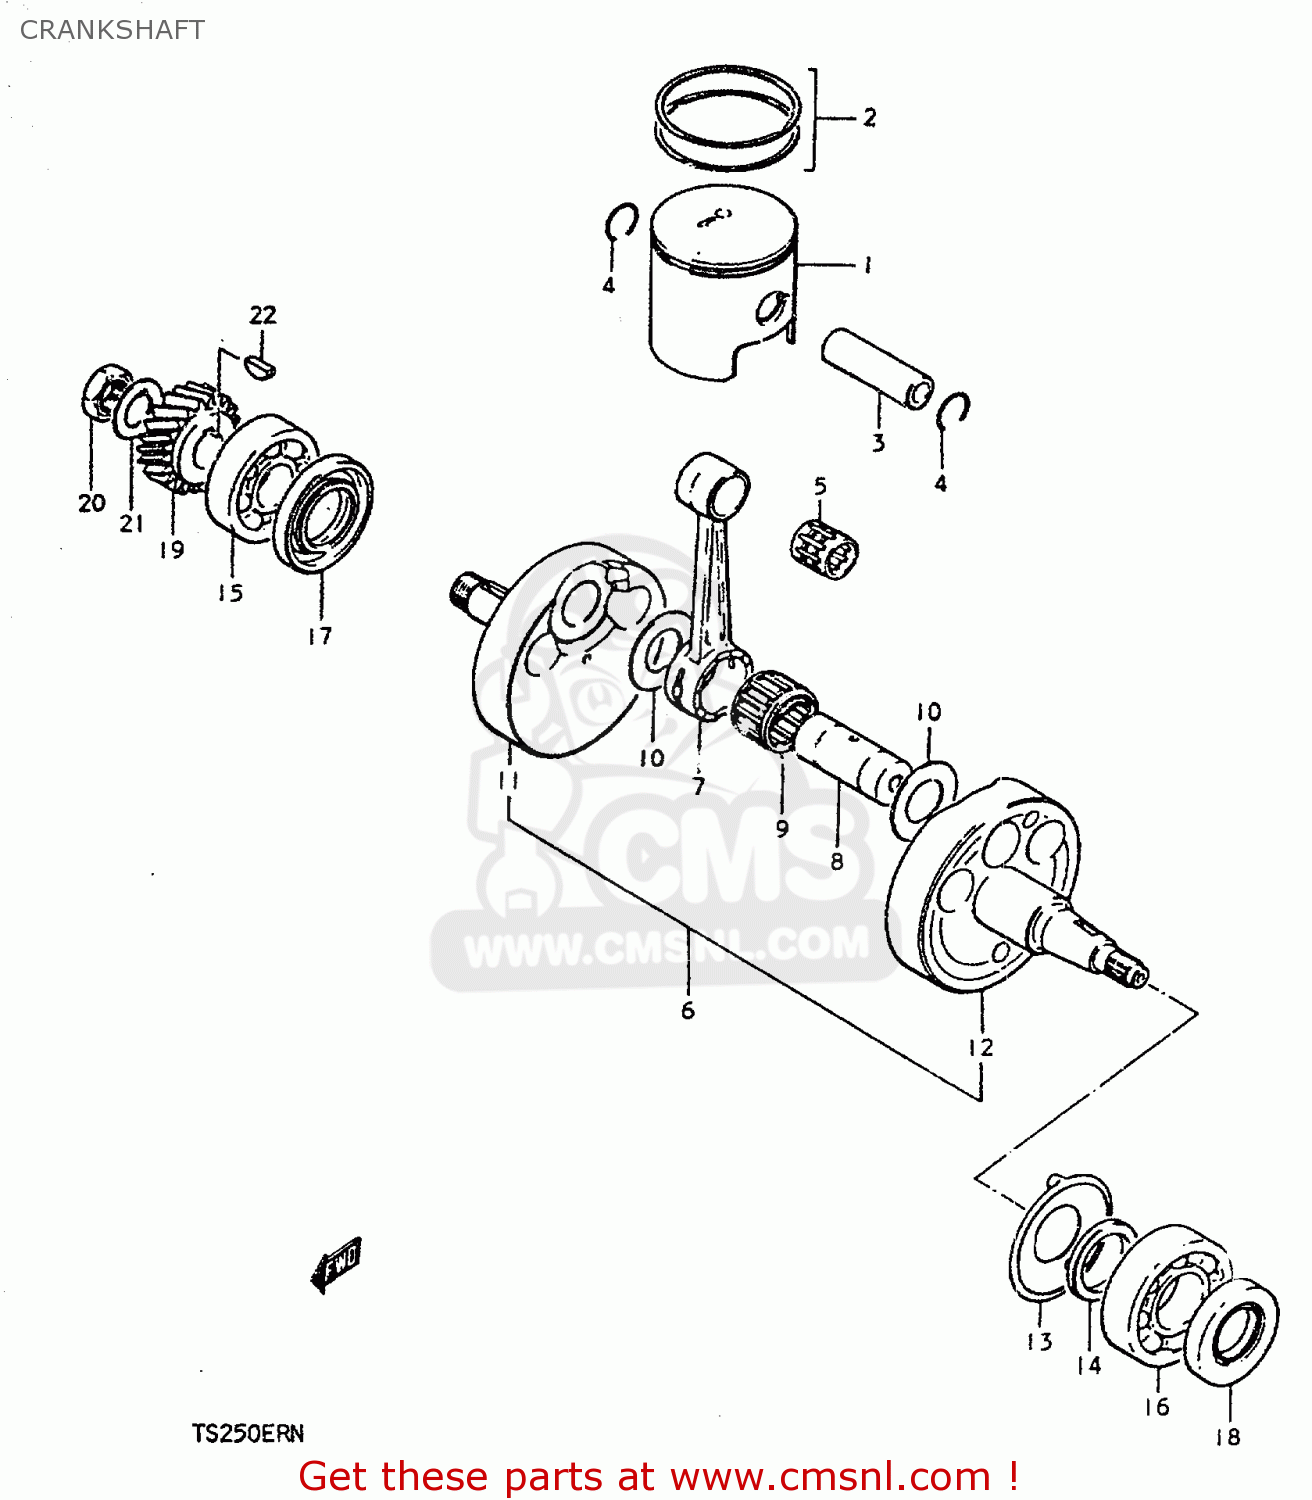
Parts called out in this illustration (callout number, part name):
1	PISTON
2	RING SET,PISTON
3	PIN,PISTON (18MM)
4	CIRCLIP,PISTON PIN
5	BEARING
6	CRANKSHAFT ASSEMBLY
7	ROD,CONNECTING
8	PIN,CRANK
9	BEARING(25X31X20)
10	WASHER(25X40X1)
11	CRANKSHAFT,RIGHT
12	CRANKSHAFT,LEFT
13	PLATE,CRANKSHAFT OIL GUIDE
14	SPACER (30X45X4.8)
15	BEARING
16	BEARING(30X72X19)
17	SEAL,OIL(35X62X9)
18	OIL SEAL
19	GEAR,PRIMARY DRIVE
20	NUT
21	WASHER
22	KEY
